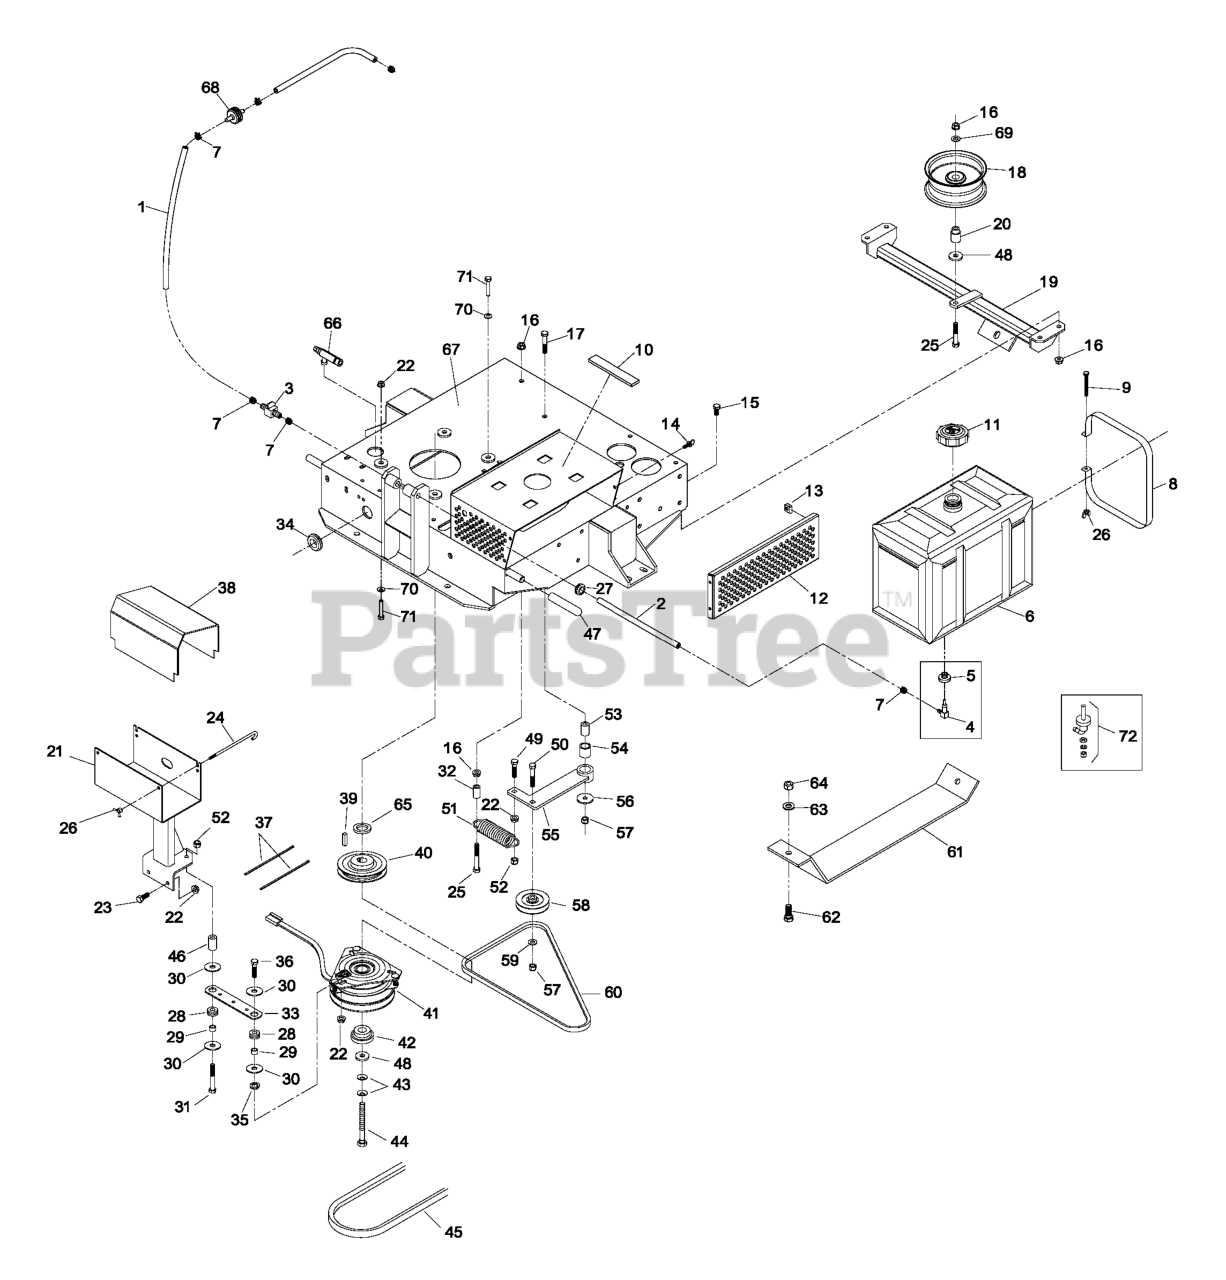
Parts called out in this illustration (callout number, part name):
1	HOSE-FUEL
3	VALVE-FUEL
4	ELBOW-TANK, FUEL
6	ASM,FUEL TANK
9	SCRW,MACH CRPH
10	PAD,PLASTIC TANK
11	CAP-FUEL
13	NUT,RETNR UTYP 1/4-20
14	SCREW,REGTHMB,
15	SCREW-HH
16	NUT-HHF, WHIZ
17	SCREW-HH
19	WLD,CROSSMEMBER
20	BUSHING,IDLER
21	WLD,BATTERY MOUNT
23	SCREW-HH
24	BOLT - HOLD DOWN
25	SCREW-HH
26	WINGNUT
27	GROMMET
28	GROMMET
31	SCREW-HH
33	STRAP-CLUTCH, BRAKE
34	GROMMET
35	WASHER-LOCK
36	SCREW-HH
37	TIE-PLASTIC
38	COVER,BATTERY W/DECAL
40	SHEAVE,4.25 OD A
41	KIT, CLUTCH W/TIES
42	BUSHING,CLUTCH KEEPER
43	WASHER-SPRING
44	SCREW-HH
45	BELT,DECK DRIVE
47	GRIP-LEVER, DRIVE
49	Bolt-Carriage 5/16-18 X 1 1/4
50	SCREW-CARR
51	SPRING,EXTENSION
52	NUT-LOCK, NI
53	BUSHING,STEEL
54	BUSHING,IDLER ARM
55	WLD,IDLER ARM HYDRO
57	NUT-LOCK, NI
58	IDLER,PULLEY
59	WASHER-FLAT
60	BELT,A TRANS DRIVE
61	PLATE-SKID
62	SCREW-HH
63	WASHER-LOCK
64	NUT-HH
65	SPACER-CRANKSHAFT
66	VALVE-DRAIN, OIL
67	DECK,ENGINE W/DECALS
68	Kohler Part No. 2405002 Fuel Filter
69	WASHER-FLAT
70	WASHER-SPRING
71	SCREW-HH
72	FITTING-FUEL, BULKHEAD
